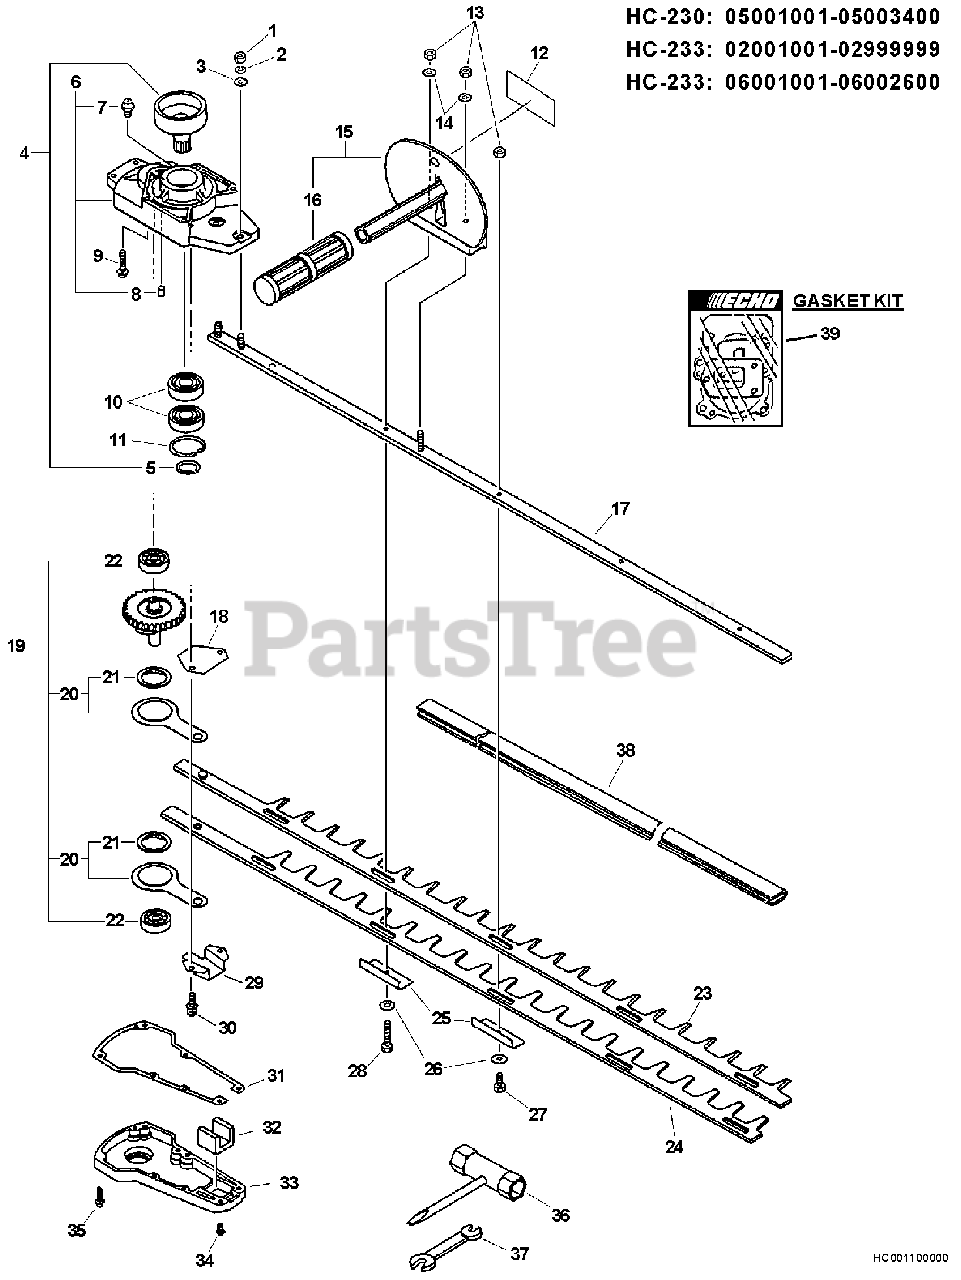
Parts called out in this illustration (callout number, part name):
1	LOCKNUT - 6
2	LOCKWASHER - 6
3	WASHER - 6
4	DRUM, CLUTCH
5	RING, RETAINING - 16
6	CASE, GEAR
7	FITTING, GREASE
8	PIN - LOCATING
9	SCREW - 5X30
10	BEARING, BALL - 6003
11	RING, RETAINING - 35
12	LABEL - CAUTION
13	LOCKNUT - 6
14	WASHER - 6
15	HANDLE ASSY - FRONT
16	GRIP, HANDLE
17	SUPPORT, BLADE
18	PLATE, GUIDE
19	GEAR ASSY
20	CONNECTING ROD ASSY
21	BEARING, NEEDLE
22	BEARING, BALL - 6200
23	BLADE - UPPER
24	BLADE - LOWER
25	INSULATOR
29	GUIDE, BLADE
30	SCREW - 5X14
31	GASKET, GEAR CASE
32	SEAL, FELT
33	LID, GEAR CASE
34	SCREW - 4X14
35	SCREW - 4X22
36	T-WRENCH - 13X19mm
37	SPANNER - 8X10mm
38	COVER, BLADE
39	GASKET KIT
